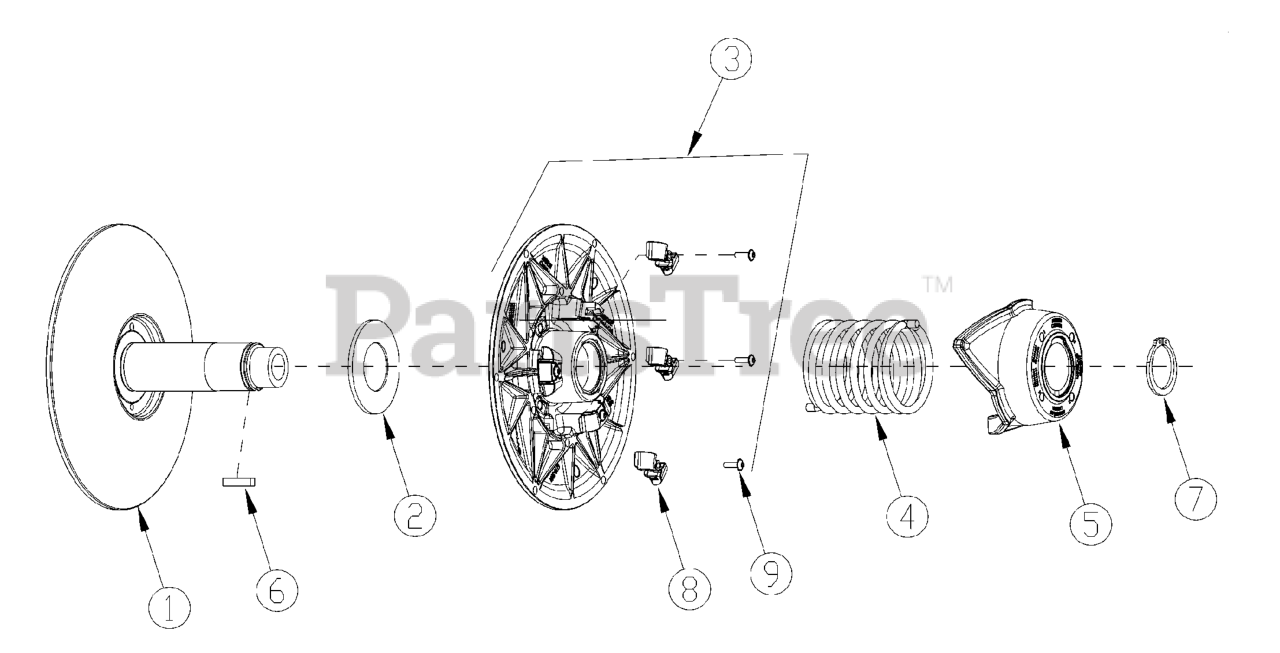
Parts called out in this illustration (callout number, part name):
1	FIXED FLANGE
2	SHIM WASHER
3	SLIDING FLANGE
4	SPRING
5	CAM
7	SNAP RING
9	HEX. SOCKET BUTTON HEAD
